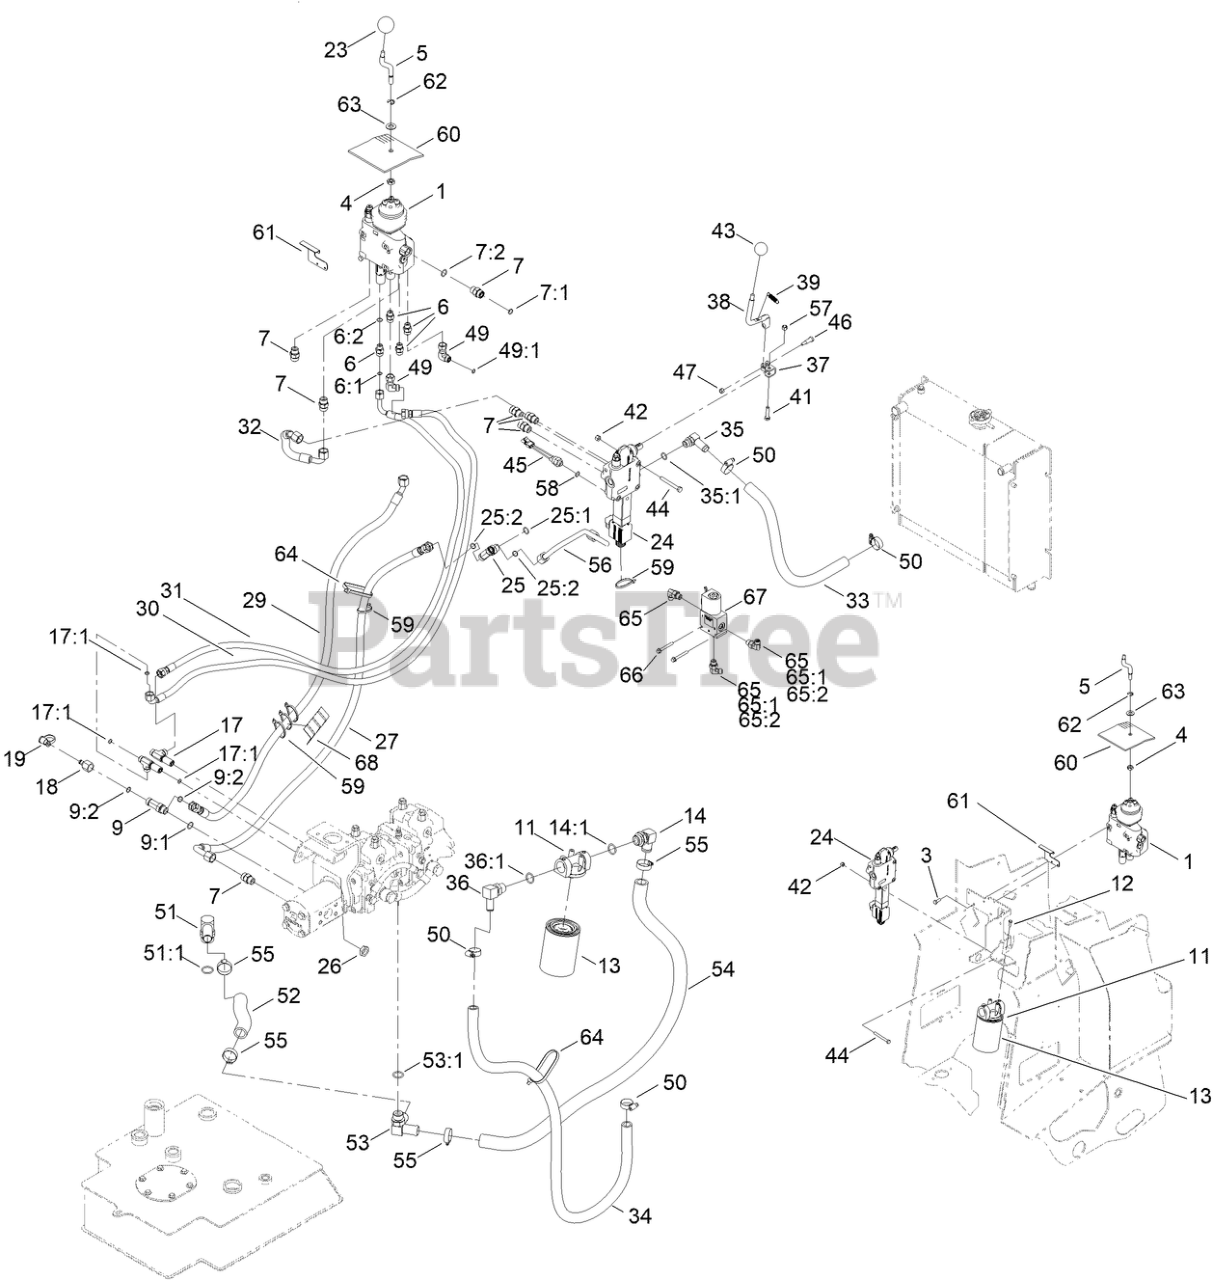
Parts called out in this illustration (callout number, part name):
1	VALVE-2 SPOOL
3	SCREW-HH
5	SHAFT-HANDLE, LIFT/TILT
6	FITTING-STRAIGHT
6:1	O-RING
6:2	O-RING
7	FITTING-STRAIGHT
7:1	O-RING
7:2	O-RING
9	FITTING-TEE
9:1	O-RING
9:2	O-RING
11	HEAD-FILTER
12	SCREW-HH
13	FILTER-OIL
14	FITTING-90
14:1	O-RING
17	FITTING-TEE, BULKHEAD
17:1	O-RING
18	FITTING
19	CAP-DUST
24	VALVE-AUX, DOUBLE DETENT
25	FITTING-HYD, TEE
25:1	O-RING
25:2	O-RING
26	NUT-LOCK
27	HYD HOSE ASM
29	HYD HOSE ASM
30	HYD HOSE ASM
31	HYD HOSE ASM
32	HYD HOSE ASM
33	HOSE-RETURN
34	HOSE-RETURN
35	FITTING-ELBOW, 90
35:1	O-RING
36	FITTING-ELBOW, 90
36:1	O-RING
37	BRACKET-AUXILARY
38	HANDLE ASM
39	SPRING-EXTENSION
41	SCREW-HH
42	NUT-LOCK, NI
44	SCREW-HH
45	SWITCH-BALL
46	BOLT-SHOULDER
47	NUT-LOCK, NI
49	FITTING-HYD, 90 DEG
49:1	O-RING
50	CLAMP-HOSE
51	FITTING-HYD, 90 DEG
51:1	O-RING
52	HOSE-SUCTION
53	CONNECTOR
53:1	O-RING
54	HOSE-RETURN
55	CLAMP-HOSE
56	HYDRAULIC TUBE ASM
57	NUT-LOCK, NI
58	O-RING
59	TIE-CABLE
60	DEFLECTOR-AIR
61	BRACKET-DEFLECTOR
62	RING-RETAINING
63	WASHER-PIVOT
64	TIE-CABLE
65	FITTING-ELBOW, 90 DEG
65:1	O-RING
65:2	O-RING
66	SCREW-HHF
67	SOLENOID VALVE
68	PROTECTOR-HOSE
